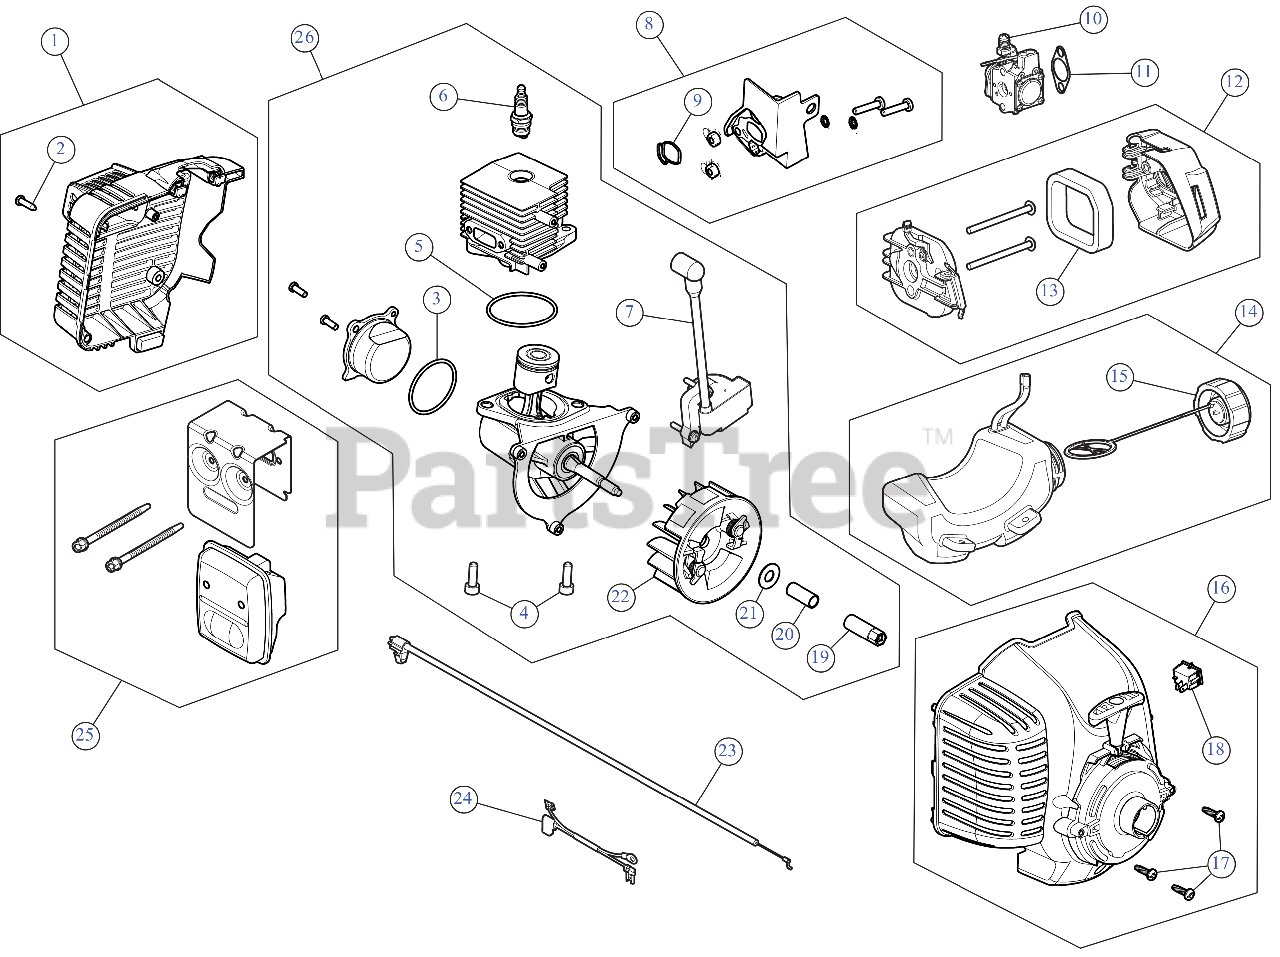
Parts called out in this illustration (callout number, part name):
1	HOUSING ASSEMBLY RR
2	SCREW, #8-16X.750 PH
3	O-RING SEAL CRANKCASE
4	SCREW 5/16-18x3/4 T40
5	O-RING SEAL CYLINDER
6	SPARK PLUG 14MM
7	RFI MODULE ASSEMBLY
8	INTAKE ASSEMBLY
9	INSL/CYL SEAL
10	CARB ASSEMBLY
11	GASKET CARB
12	AIR CLEANER
13	AIR FLITER
14	FUEL TANK
15	FUEL CAP
16	STARTER HOUSING ASSEMBLY
17	SCREW #
18	SW, MOMENTARY ON/O
19	POWER SHAFT ADAPTER
20	SPACER CRANKSHAFT
21	FLAT WASHER
22	FLYWHEEL ASSEMBLY
23	THROTTLE CABLE
24	SHORT WIRE LEAD
25	MUFFLER ASSEMBLY
26	SHORT BLOCK
